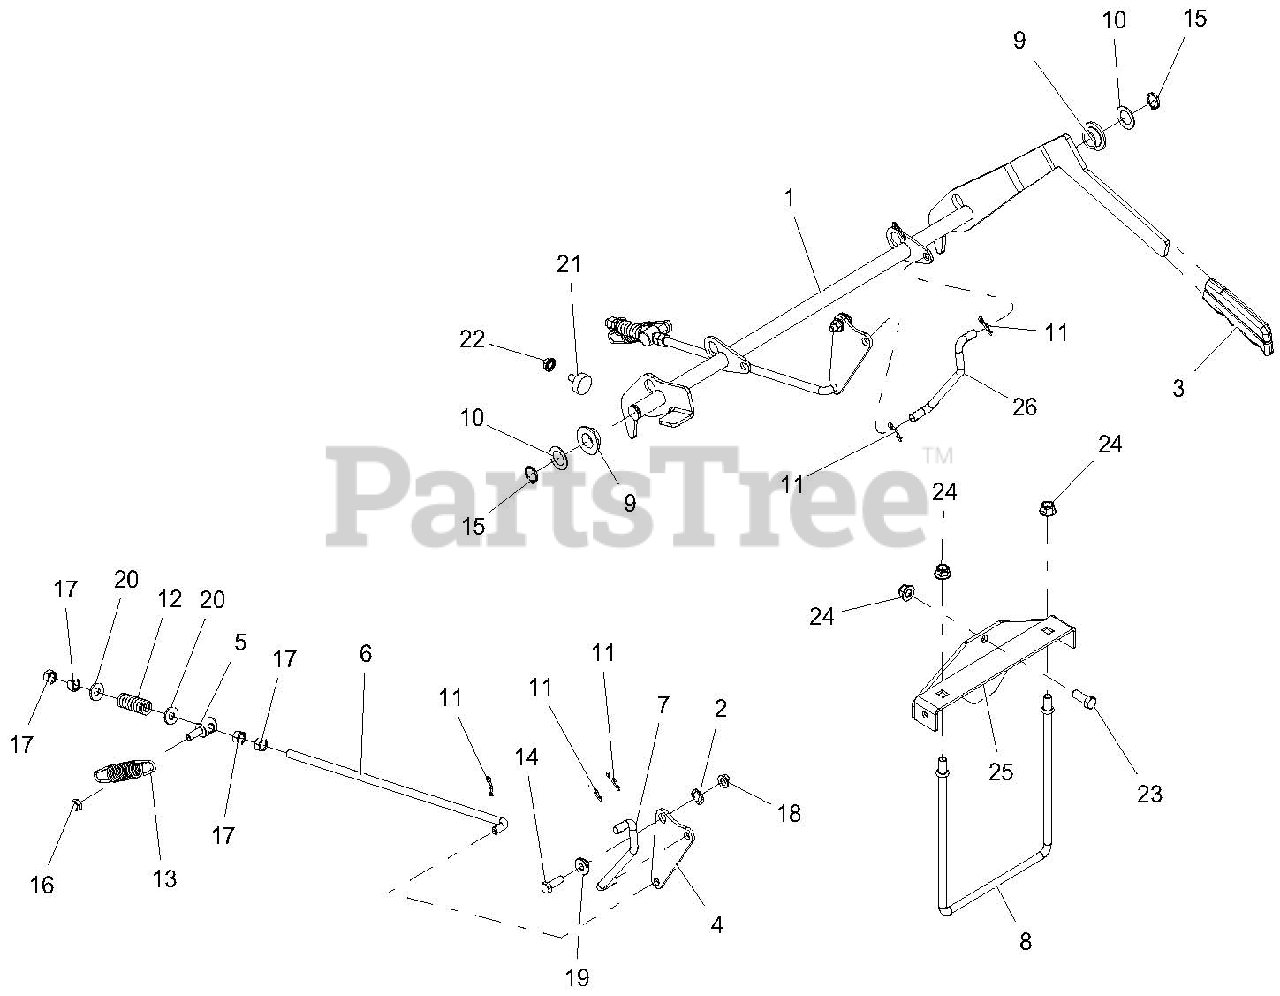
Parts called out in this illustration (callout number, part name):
1	WLDMT, PT200/400 PARK BRAKE - GAS
2	WAVE WASHER .531X.781X.125 FH
3	GRIP, PARKING BRAKE
4	PLATE, BRAKE PIVOT-BLACK
5	TRUNNION, .31-18
6	ROD, BRAKE ADJ.
7	LINKAGE, RH BRAKE ACTUATING
8	ROD, BRAKE MTG
9	BSHG, FLANGE .762 X 1.48 X .44 NYLON
10	WSHR-HDND-THRST
11	PIN-HAIR, ENDRIES #25 YWZC
12	SPRG, COMPRESSION
13	SPRG, TENSION .105 X .850 X 4.880
14	BLT-HEX .31-18X1.00 GR5 YWZC
15	RG-RTNG-EXT .750x.078
16	@NUT-LK-CTR-JAM .31-18 YWZC
17	NUT-HEX .38-16 YWZC
18	NUT, LK-TOP-FLG .312-18 YWZC
19	BSHG, FLG .32X.500.344X.880
20	WSHR-FL-STL.38X.875X.083 YWZC
21	BUMPER, RUBBER
22	@NUT-SPNLK-FLG .312-18 YWZC
23	BLT-HEX .38-16X1.00 GR5 YWZC
24	NUT-LK-NYL-FLG .38-16 YWZC
25	WMT, SPRING ANCHOR BRKT-BLACK
26	LINKAGE, LH BRAKE ACTUATING
